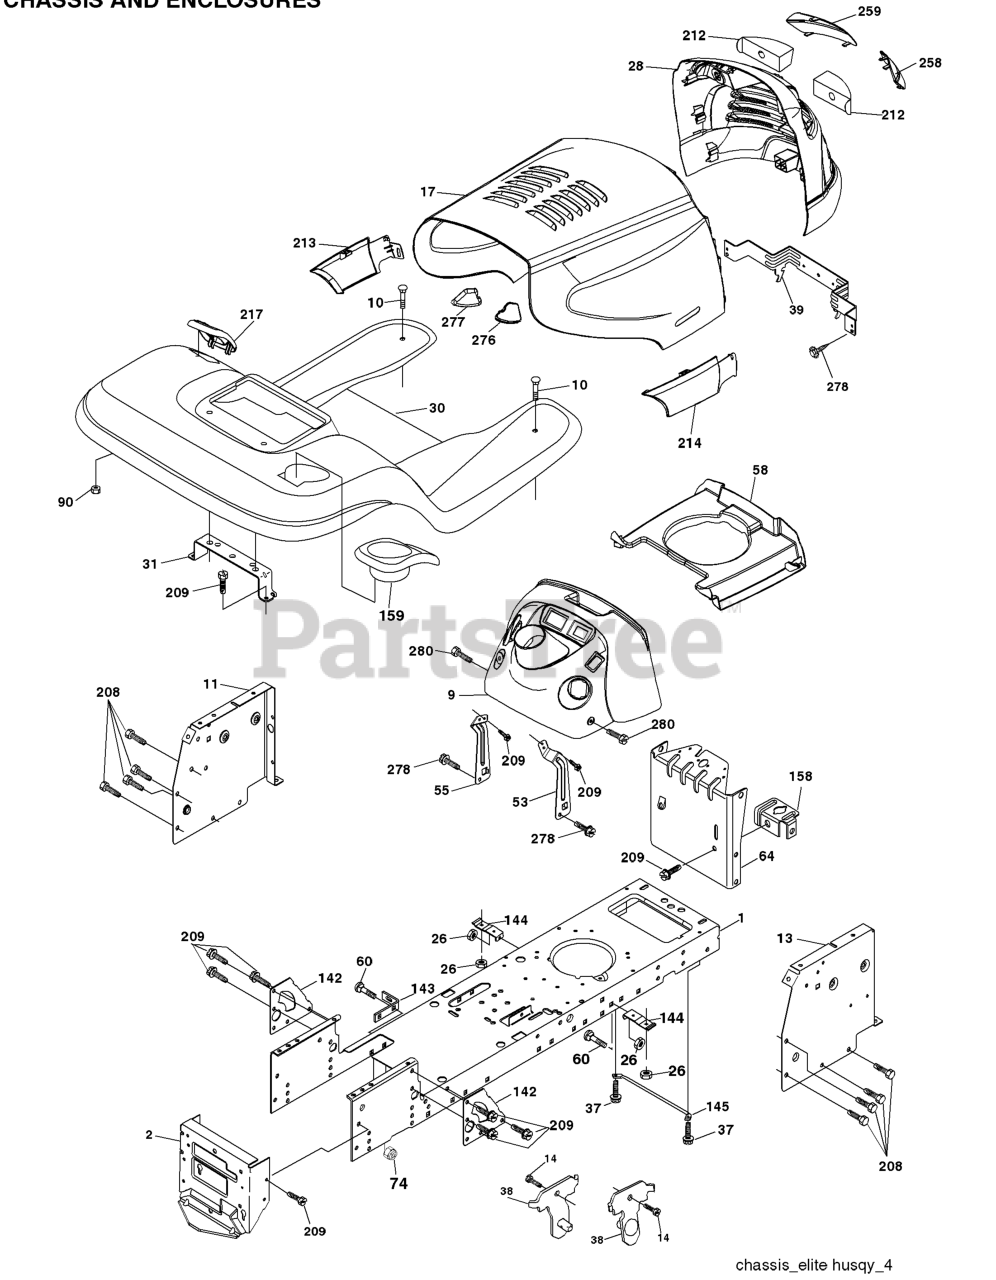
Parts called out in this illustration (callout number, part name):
1	CHASSIS STAMPING
2	DRAWBAR, 12GA
9	DASH
10	BOLT D
11	PANEL.DASH.LH.LTX
13	PANEL DASH RH
14	SCREW LT
17	HOOD
26	NUT
28	GRILL/LENS ASSY ( YT MODEL)
30	FENDER STL W/CUPHOLDER
31	BRACKET.SUPPORT.FENDER
37	Screw Thdrol 5/16-18 x 1/2 TYT
38	BRACKET.ASM.PIVOT.MOWER.REAR
39	BRACKET PIVOT LASER
53	BRACKET DASH RH
55	BRACKET DASH LH
58	AIR DUCT ENGINE
60	Bolt Rdhd Sqnk 3/8-16 unc x 3/4
64	DASH LOWER
90	NUT.PUSH.3/16
142	PLATE REINFORCEMENT
143	BRACKET, SWAYBAR CHASSIS
144	BRKT, FOOT REST
145	ROD PIVOT CHASSIS/HOOD
158	BRACKET PARKING BRAKE
159	CUPHOLDER
208	SCREW 3/8-16X1/2
209	SCREW, 3/8-16X3/4
212	INSERT LENS
213	SKIRT SIDE LH
214	SKIRT SIDE RH
217	CONSOLE FUEL WINDOW
258	LENS ELITE CLEAR RH
259	LENS ELITE CLEAR LH
276	BUMPER HOOD RH
277	BUMPER HOOD LH
278	SCREW
280	SCREW 3/8-16X1
